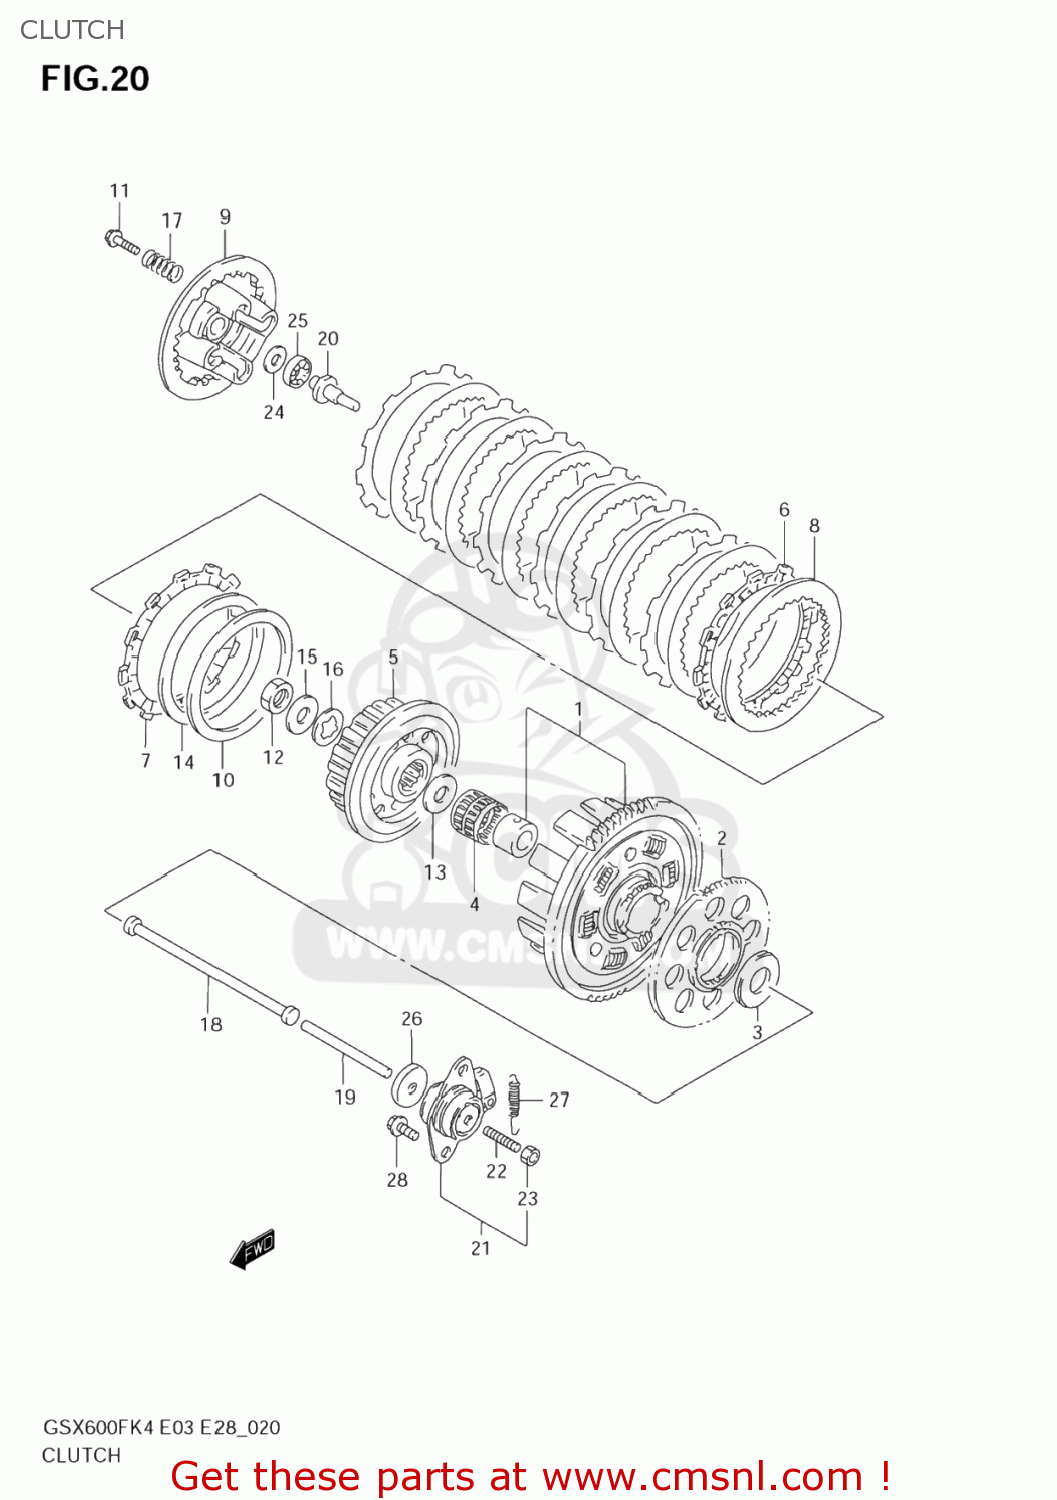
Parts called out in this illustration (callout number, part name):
1	GEAR ASSY,PRI DRIVEN(NT:75)
2	GEAR,GENERATOR DRIVE
3	WASHER(25X54X2.5)
4	BEARING(35X40X35.8)
5	HUB,CLUTCH SLEEVE
6	PLATE,CLUTCH DRIVE (NAS)
7	PLATE,CLUTCH DRIVE(T:3.5) (NAS)
8	PLATE,CLUTCH DRIVEN (NAS)
9	DISC,CLUTCH PRESSURE
10	SEAT,WAVE WASHER(T:1.4)
11	BOLT(6X30)
12	NUT
13	WASHER(25X50X2.5)
14	WASHER
15	WASHER
16	SHIM(22X36X1)
17	SPRING,CLUTCH
18	ROD,CLUTCH PUSH,R
19	ROD,CLUTCH PUSH,L
20	PIECE,CLUTCH PUSH
21	SCREW ASSY,CLUTCH RELEASE
22	SCREW(6X25)
23	NUT
24	WASHER(15.5X28X1)
25	BEARING(15X28X2)
26	SEAL,OIL(6X34X5.5)
27	SPRING
28	BOLT
